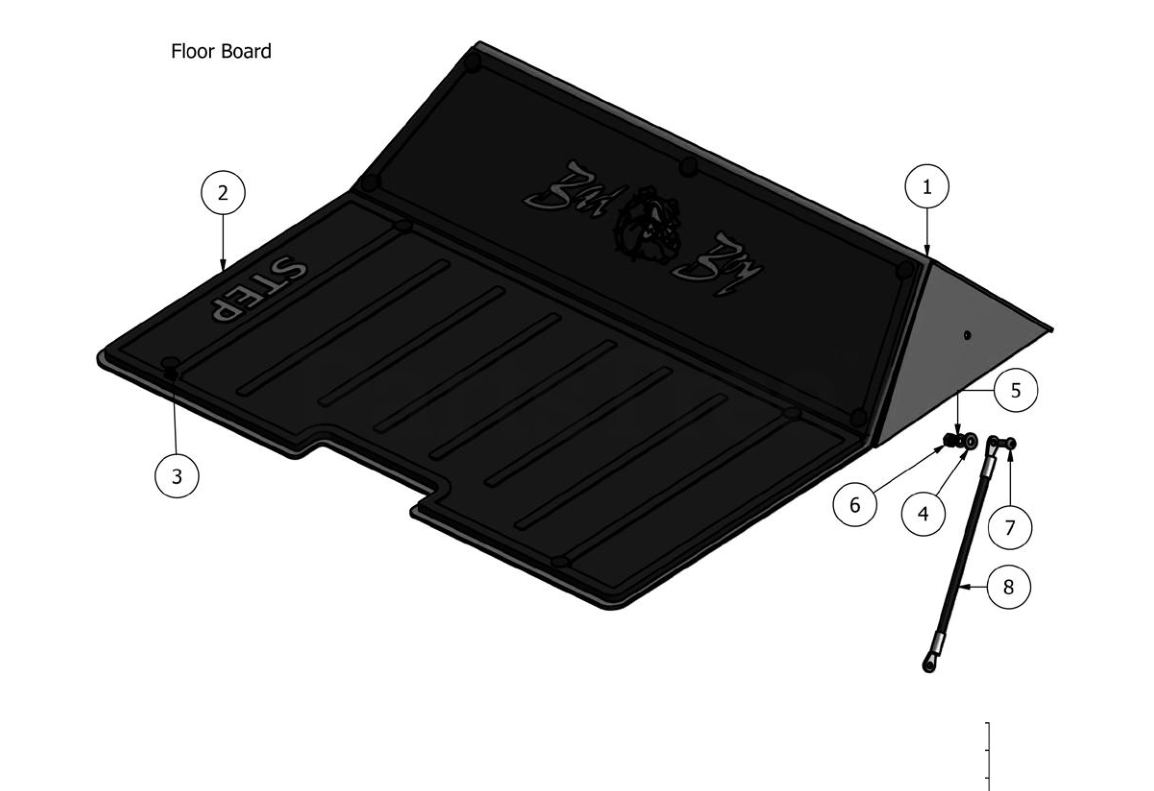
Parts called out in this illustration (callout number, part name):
1	Floor Panel
3	Ratchet Fastener
4	1/4" Flat Washer
5	1/4" Lock Washer
6	1/4" Hex Nut
7	1/4" x 5/8" Buttonhead Bolt
8	Floor Panel Cable
